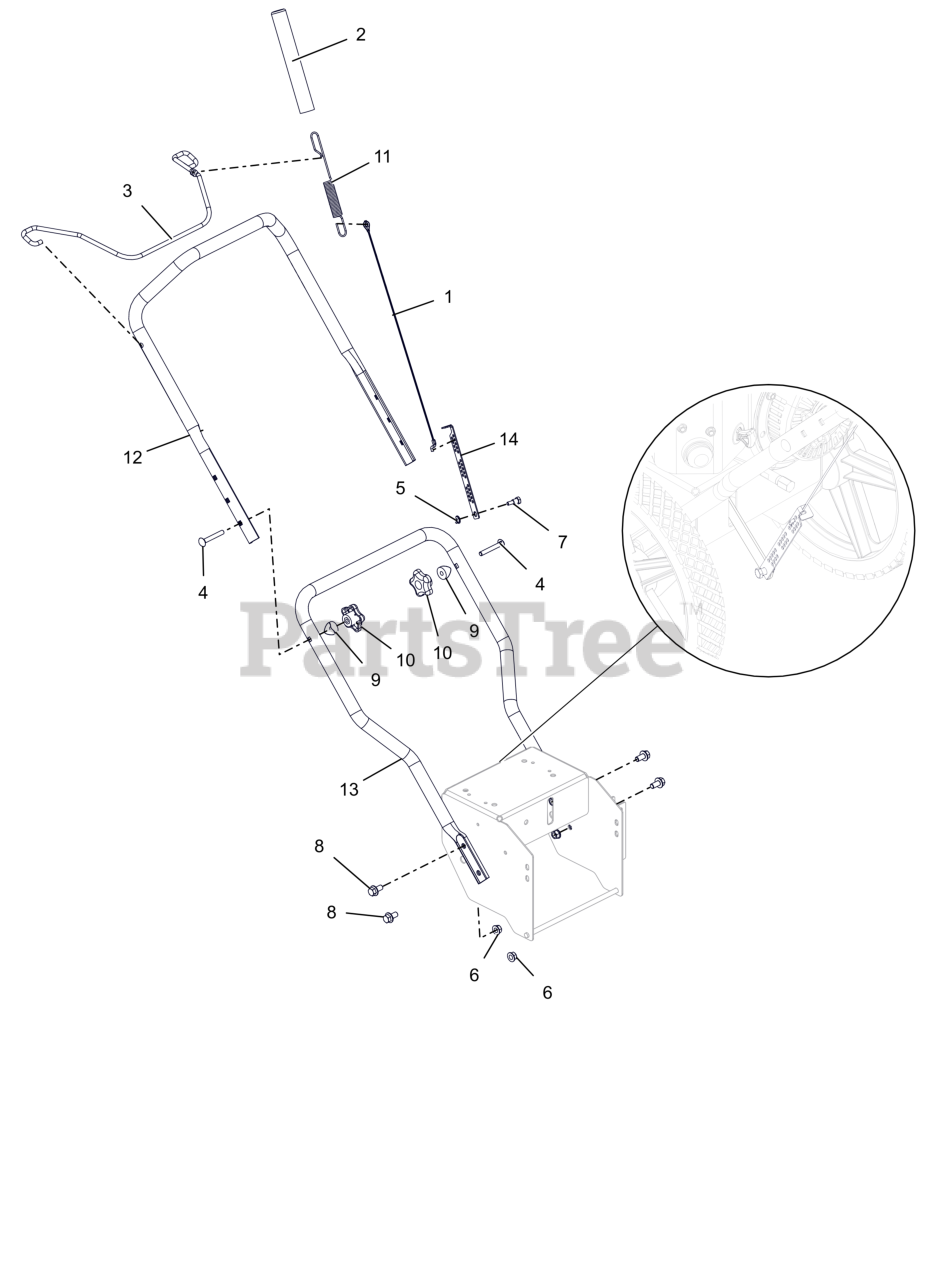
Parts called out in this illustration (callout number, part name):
1	CABLE, AUGER
2	COVER, CABLE SPRING
3	BAIL, AUGER (BLACK)
4	BLT, RHSN .31-18X2.25 G5 ZCC
5	NUT-LK-CTR-FLG .25-20 ZC120
6	NUT-LK-CTR-FLG .375-16 GF ZCC
7	BOLT, SHLDR -.375 X .375 X .25-20
9	SPACER, HANDLEBAR
10	KNOB, STAR, 5/16-18UNC
11	SPRG, EXT .100X.740X8.175
12	UPPER HANDLEBAR W/DECAL
13	LOWER HANDLEBAR W/DECAL
14	PLATE, CABLE ADJUSTMENT (BLACK)
